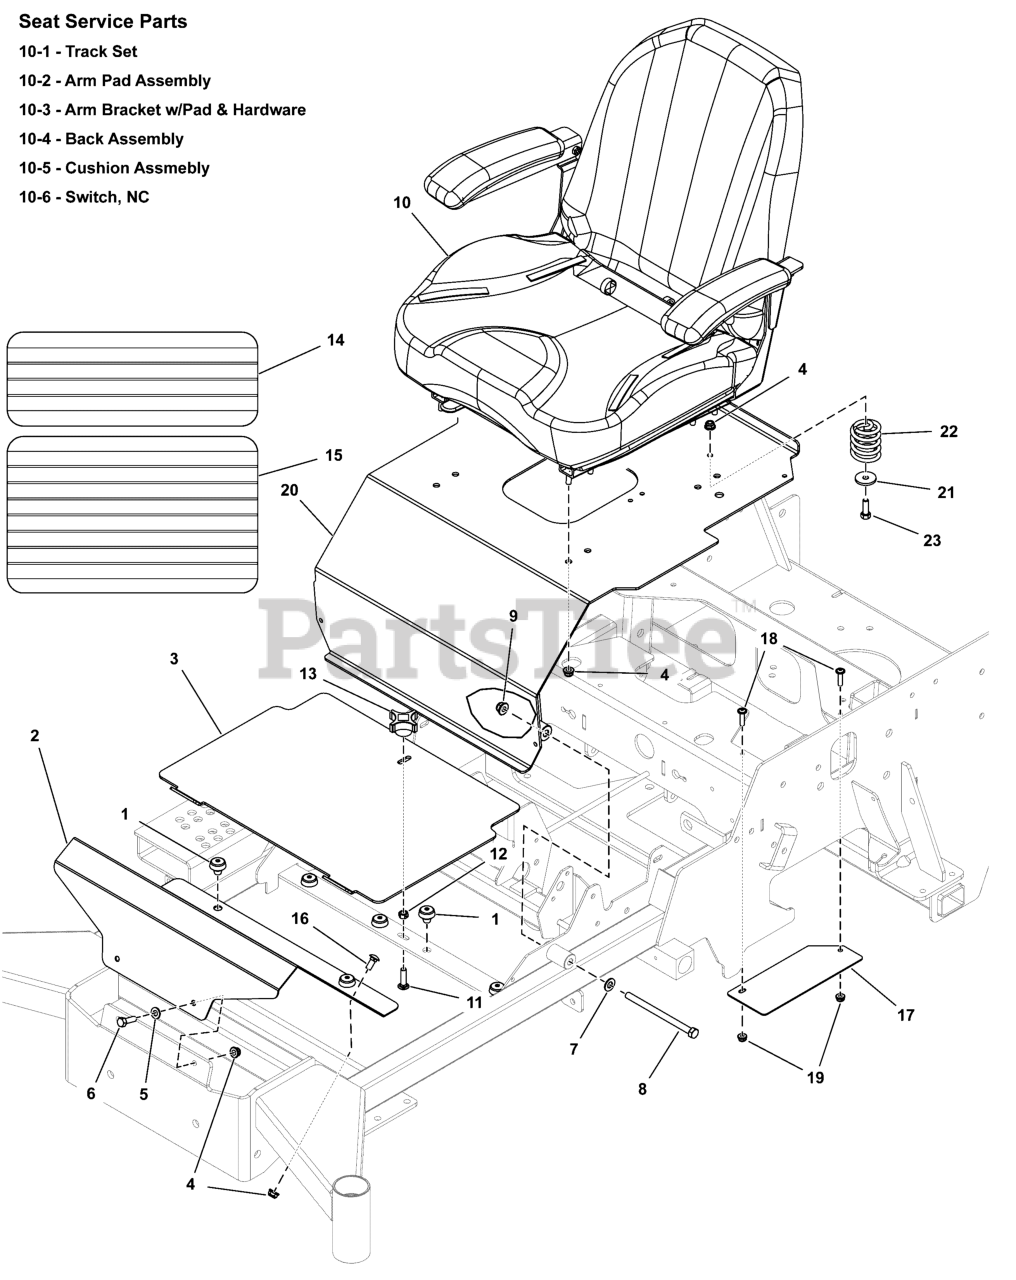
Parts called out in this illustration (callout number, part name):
1	MNT, VBRTN, RBBR
2	PLATE, FLOOR RIGID, S125XT - RED
3	PLATE, FLOOR, REMOVABLE, S125XT - RED
4	NUT, 5/16-18 HEX NYLOCK FLANGE NUT
5	WASHER, 5/16" SAE
6	BOLT, 5/16-18 X 1" GRD5 YZ
7	WASHER, 3/8 SAE
8	BOLT, 3/8-16 X 5-1/2" GD5 CZ
9	NUT, 3/8 - 16 HEX NYLOCK FLANGE
10	SEAT, 907, W/ARM REST & SWITCH, NO BEAD
10-1	4" SL TRACK SET - 9" FLAT - W/HDWR
10-2	ARM PAD ASSEMBLY
10-3	ARM BRACKET W/PAD & HARDWARE
10-4	BACK ASSEMBLY
10-5	CUSHION ASSEMBLY
10-6	SWITCH, SEAT
11	BOLT, 5/16-18 X 1-1/4, CARRIAGE, GD5, CZ
12	NUT, 5/16-1/8, HEX, CNTR LK, ZINC PHOS/OIL
13	KNOB-INT THR .312-18 4-ARM 2.12WD 1.06LG
14	SAFETY WALK, FLOOR REST, 16.00 X 6.00
15	SAFETY WALK, FLOOR PLATE, S50X, 10X17.13
16	BOLT, 5/16-18 X 3/4, CARRIAGE, GD5, CZ
17	PLATE, SEAT BELT GUARD - S125XT - BLK
18	SCREW, FLANGE, ALLEN HD, 1/4-20 X .75 SS
19	NUT, 1/4-20 Hex Nylock Flange
20	ASSM, SEAT PLATE W/DECALS, S125XT (2019)
21	WASHER, .34 X 1.25 X 10 GA
22	SPRING, SEAT SUPPORT
23	BOLT, 5/16-18 X 3/4 GD5
